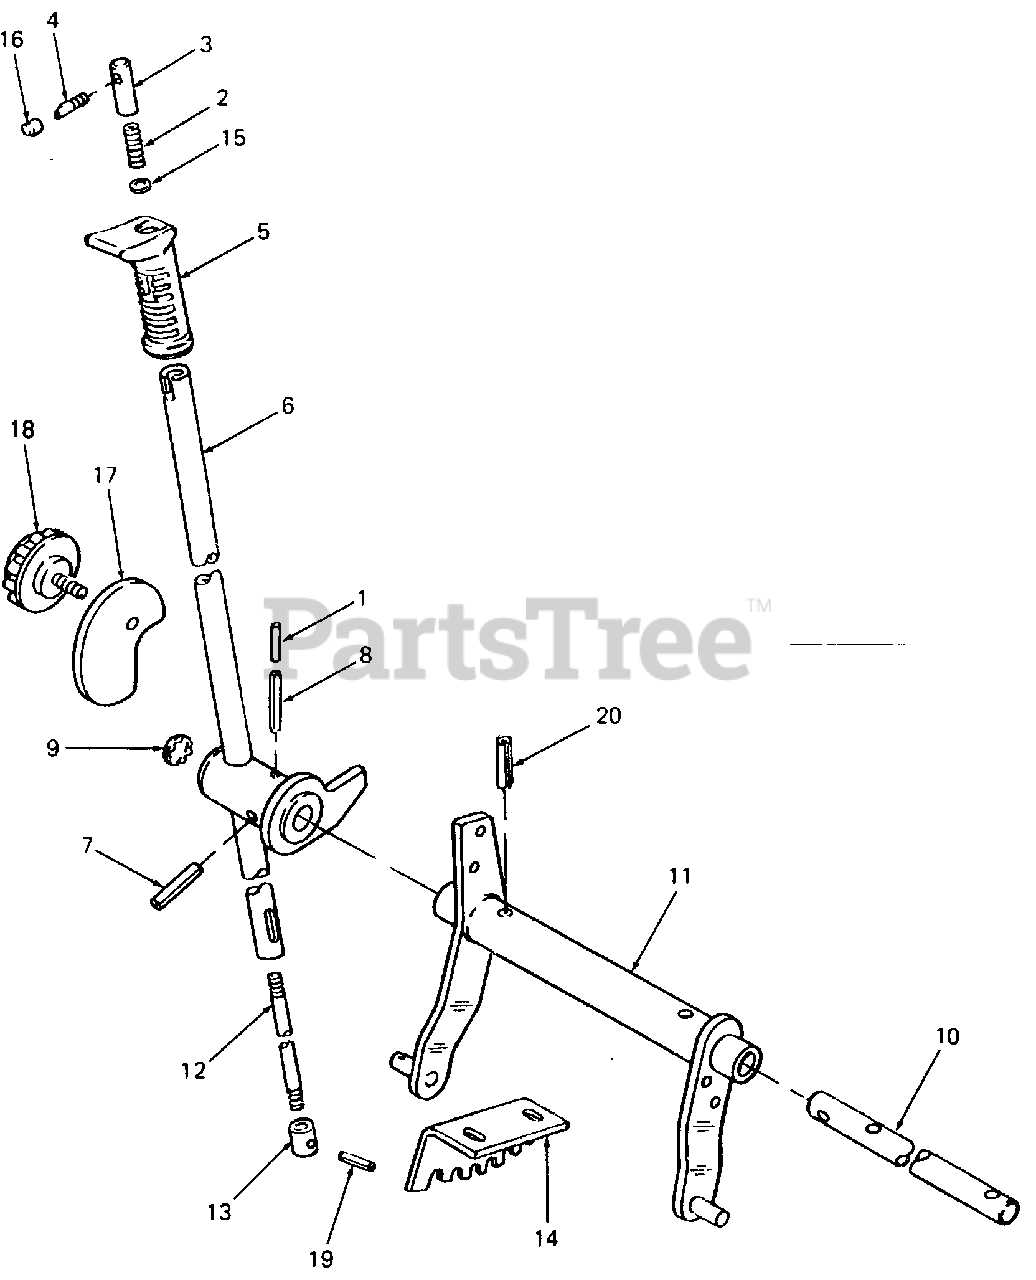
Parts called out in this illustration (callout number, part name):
1	Pointer, Lift
2	Spring, Lift Handle
3	Pin, Lift Handle Float
4	Pin, Float Lock
5	Grip, Lift Handle
6	Handle, Lift
7	Pin, Roll, 3/8 Dia X 1.5 Lg
8	Pin, Roll, 3/16 Dia X 3.0 Lg
9	Plug, Button
10	Rockshaft
11	Lift Assembly, Rockshaft
12	Rod, Handle
13	Rod, Handle Release
15	Washer, Flat, .344 X .532 X .06 Thk (HDN)
16	Cap, Float Lock Pin
19	Pin, Spirol Spring, 5/16 X 1.5 Lg
20	Pin, Roll, 3/8 Dia X 2.0 Lg
